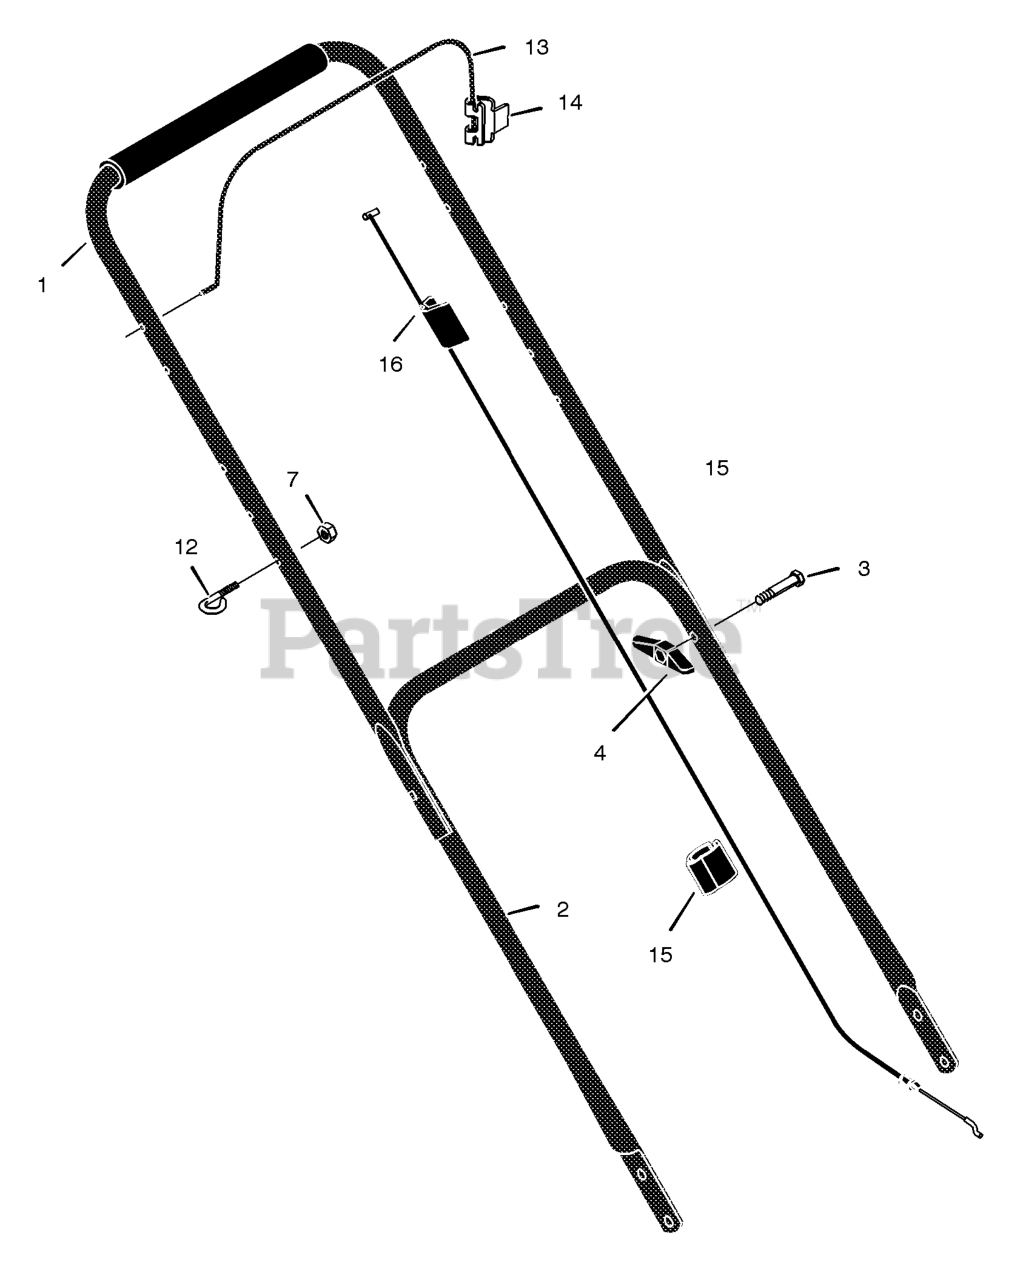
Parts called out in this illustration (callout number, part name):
1	Handle, Upper (Black)
2	Handle, Lower (Black)
4	Knob, Plastic
7	Locknut
12	Guide, Rope
13	Engine Stop Lever
14	Bracket, Stop Lever
15	Fastener, Single Cable
16	Engine Stop Cable
